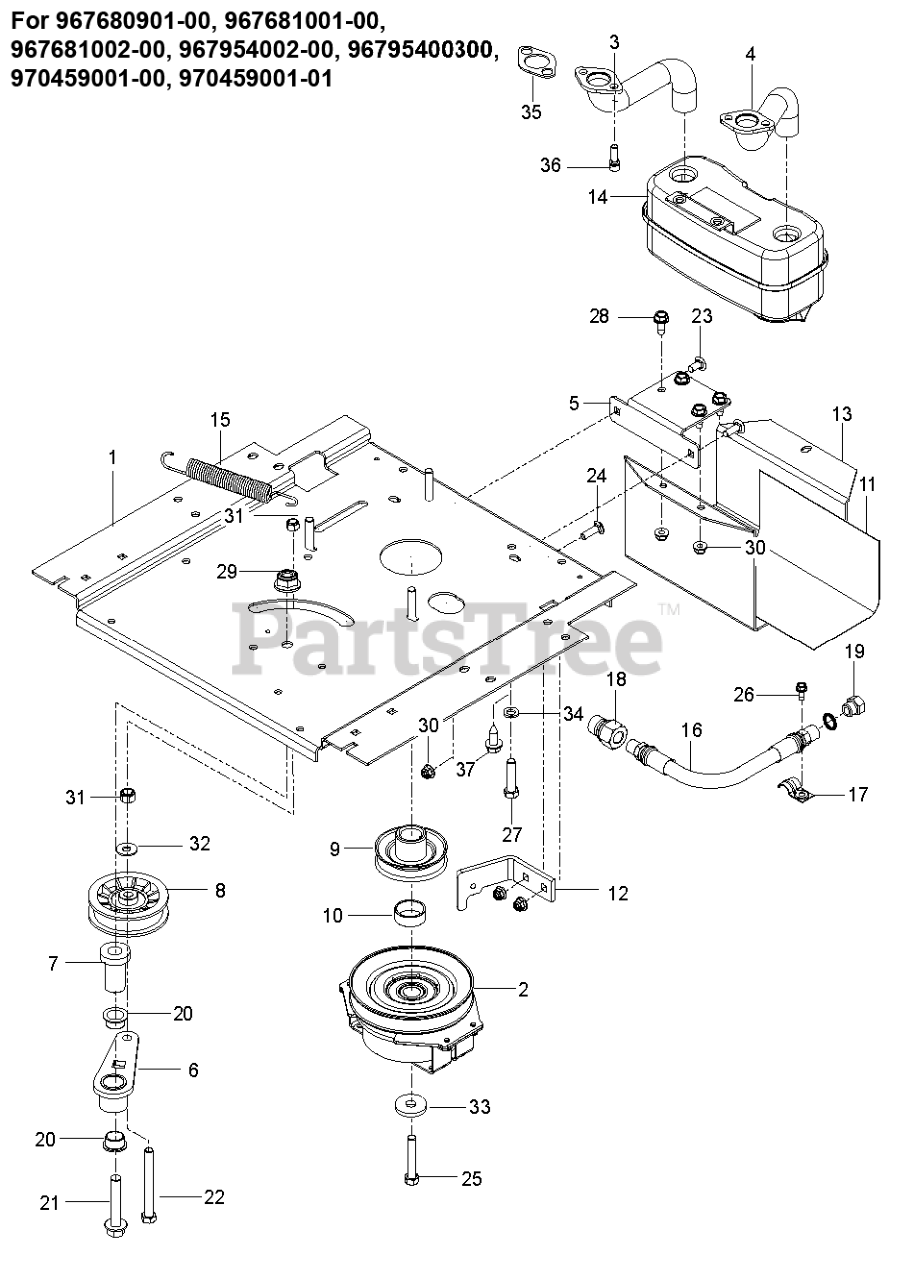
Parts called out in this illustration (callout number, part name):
1	PLATE ENGINE; RZ, 23IN BLACK
1	PLATE.ENGINE.PNT.23"FRAME.EDIP
2	CLUTCH.OGURA.5.0PD.GT1.5A-EH07
3	EXHAUST.TUBE.LH.BS/TWIN
3	TUBE.EXHAUST.RH.FR961/FR730
4	TUBE.EXHAUST.LH.FR961/FR730
4	EXHAUST.TUBE.RH.B&S.TWIN.INTEK
5	BRACKET MUFFLER MS431BLK
6	ARM IDLER
7	SPINDLE.IDLER
8	PULLEY, IDLER RAKE & ZTR
9	PULLEY.ENGINE
10	SPACER.SPACER.625 W/OGURA.LCC
11	HEAT SHIELD
12	CLUTCH.STOP.OGURA LCC.BLACK
13	GUARD.MUFFLER.WO.TOW.HITCHX431
14	MUFFLER ASM TWIN
15	SPRING, DECK DRIVE
16	HOSE.ASSEMBLY.OIL.DRAIN
17	CLAMP
18	ADAPTER, OIL DRAIN
19	PLUG OIL DRAIN
20	BEARING.FLANGED.PLASTIC.3/4ID
21	BOLT.FLANGE.1/2-13 X 2.75.GRD5
22	HCS 3/8-16X3-1/2 TAPBLT GR5 ZD
23	BOLT 5/16C X 3/4" CARRIAGE
24	RHSNB 5/16C X 1
24	BOLT
25	CLUTCH BOLT7/16-20X2.5 GR524HR
26	SCR 1/4-20X5/8 HEX SELF TAP ZD
27	BOLT, HCS 3/8-16X1-3/4
27	BOLT
28	SCREW.THDROL.5/16-18X3/4.TTY
29	NUT, 1/2-13 HEX FLG NYLOC ZD
29	5/16-18 NYLOC FLANGE NUT
30	5/16-18 NYLOC FLANGE NUT
30	NUT 3/8-16 NYLOC
31	NUT, 1/2-13 HEX FLG NYLOC ZD
31	NUT 3/8-16 NYLOC
32	WASHER.5/16.FLAT.STE.STD.
34	SLW 3/8 STD
35	GASKET.MUFFLER
36	SCREW.SOCKET.HEAD.5/16-18
37	NUT 3/8-16 NYLOC
